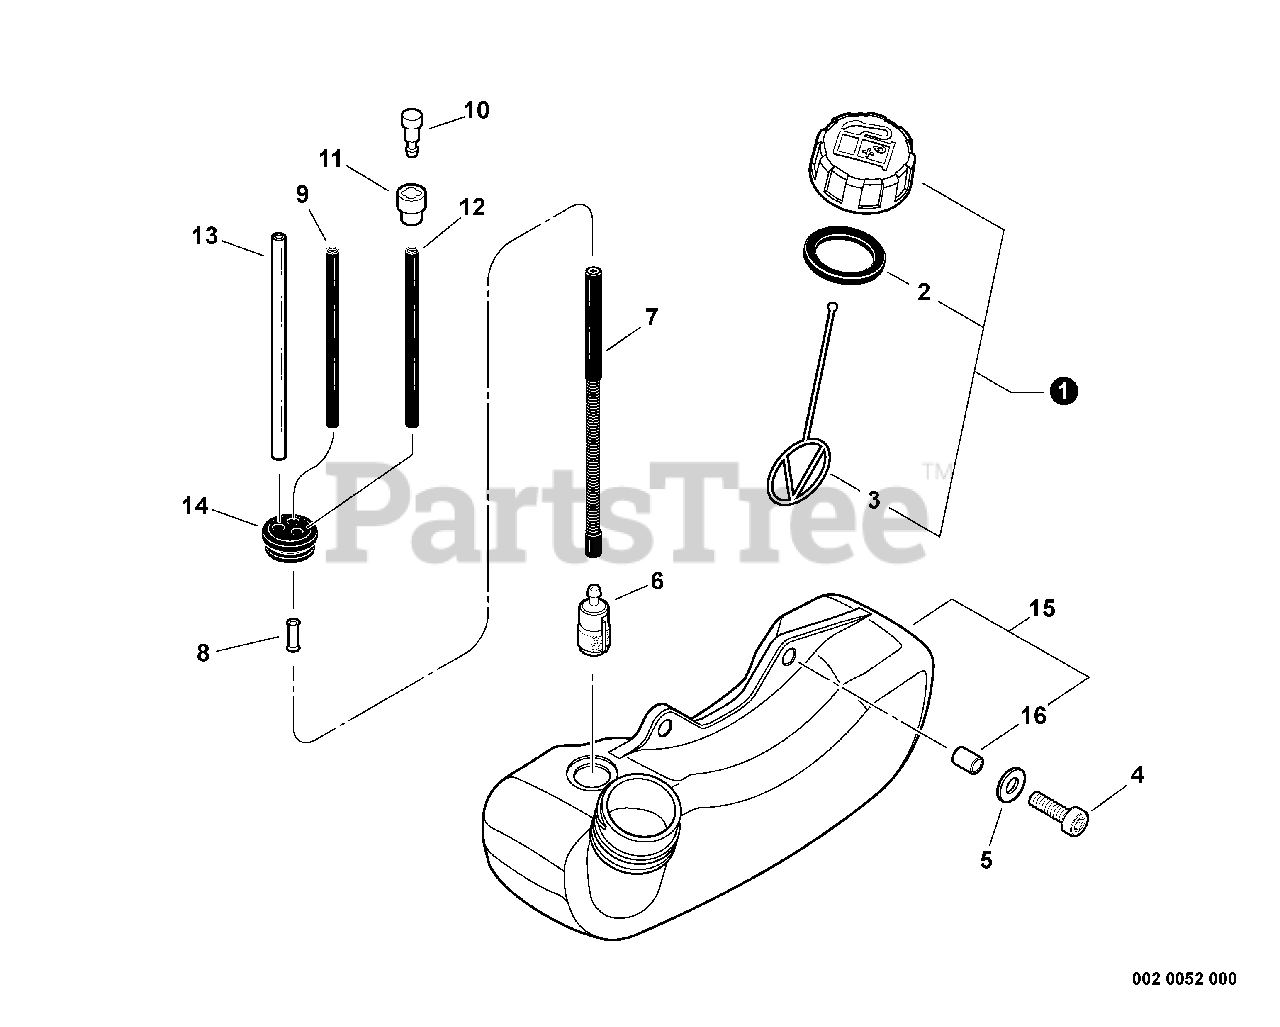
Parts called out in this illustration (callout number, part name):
1	CAP ASSY, FUEL
2	GASKET, FUEL CAP
3	CONNECTOR, CAP L= 100 MM
4	BOLT 5×16
5	WASHER 5.5×12×0.8
6	FILTER, FUEL
7	PIPE, FUEL 3×7×100 FLEXIBLE
8	CONNECTOR, PIPE
9	PIPE, FUEL 3×5×90 BLACK
10	VENT ASSY
11	HOLDER, VENT
12	PIPE, FUEL 3x-5x-70 BLACK
13	PIPE, FUEL RETURN 3×6×90 MM CLEAR
14	GROMMET, FUEL
15	TANK ASSY, FUEL
16	SPACER 6.2×7.8×6
